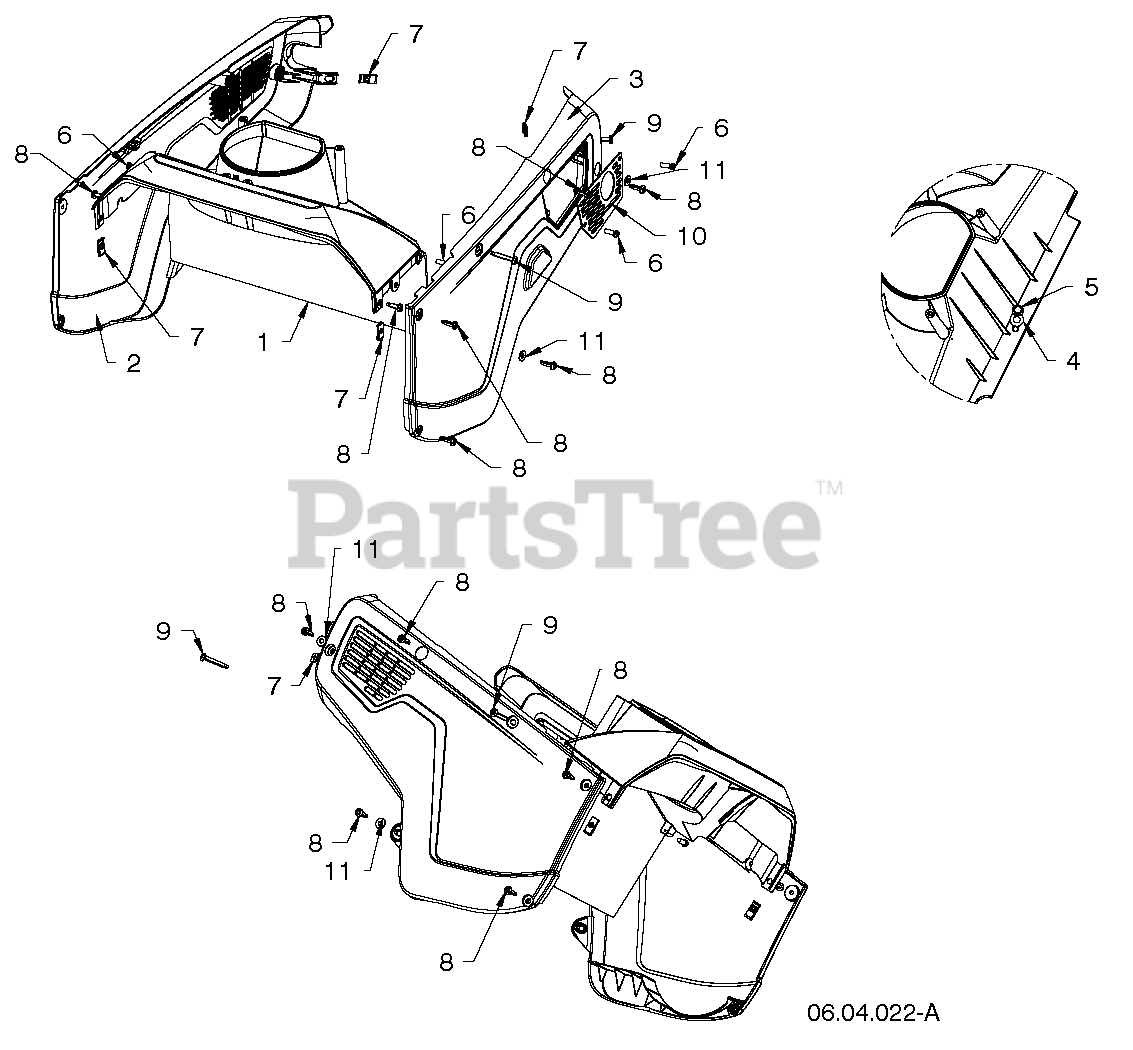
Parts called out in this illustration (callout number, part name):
1	PLENUM.AUGER.JONSERED
2	COVER.NON-DRIVE.SIDE.JONSERED
3	COVER.DRVE.SIDE.JONS BLK(2 2M)
5	BOLT.HEX.HD.WASHER.5/16-18X.75
6	SCREW.HX.13X.750
8	SCREW.PAN.HD.TORX.1/4-20X.750
9	SCREW.1/4-20.PAN.HEAD.TORX.
10	PLATE.EXHAUST.SINGLE.STAGE.SNO
11	WASHER
